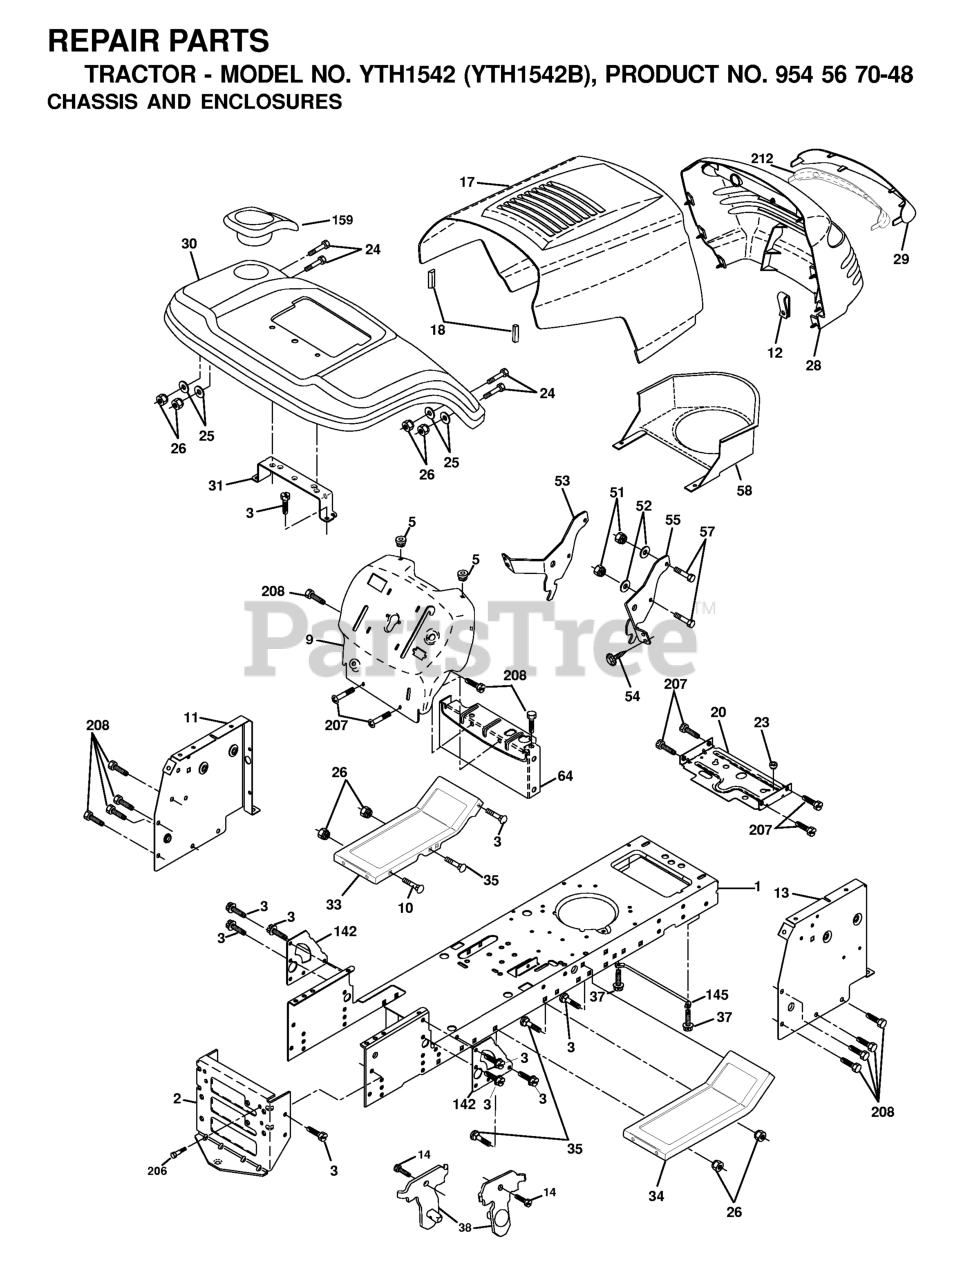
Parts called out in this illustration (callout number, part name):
1	CHASSIS STAMPING
2	DRAWBAR, 12GA
3	SCREW 3/8-16X3/4
5	BUMPER.RUBBER.HOOD
9	DASH SLKSCR
10	BOLT D
11	PANEL DASH LH
13	PANEL ASM, DASH RH
17	HOOD ASM.
18	BUMPER HOOD T
20	PLATE MTG
23	BUSHING.SNAP.NYL.BLK.
25	WASHER
26	NUT
28	GRILLE ASM
29	LENS
31	BRACKET FENDER
33	FOOT REST LH
34	FOOTREST RH
37	Screw 5/16-18 x 1/2 Hex, Self Tapping 5/16-18 x 1/2
38	BRACKET
51	LOCKNUT.NYLOC.1/4-20
53	BRACKET.GRILLE.LH
54	SCREW.HEX.WS.HD.8-18 X 7/8
57	BOLT
58	AIR DUCT P/L/LT
64	DASH LOWER
142	PLATE
145	ROD PIVOT CHASSIS/HOOD
206	SHOULDER BOLT 5/16-18TT
207	SCREW, 5/16-18 X 1/2
208	SCREW 3/8-16X1/2
212	REPL BY 532 1745-03
